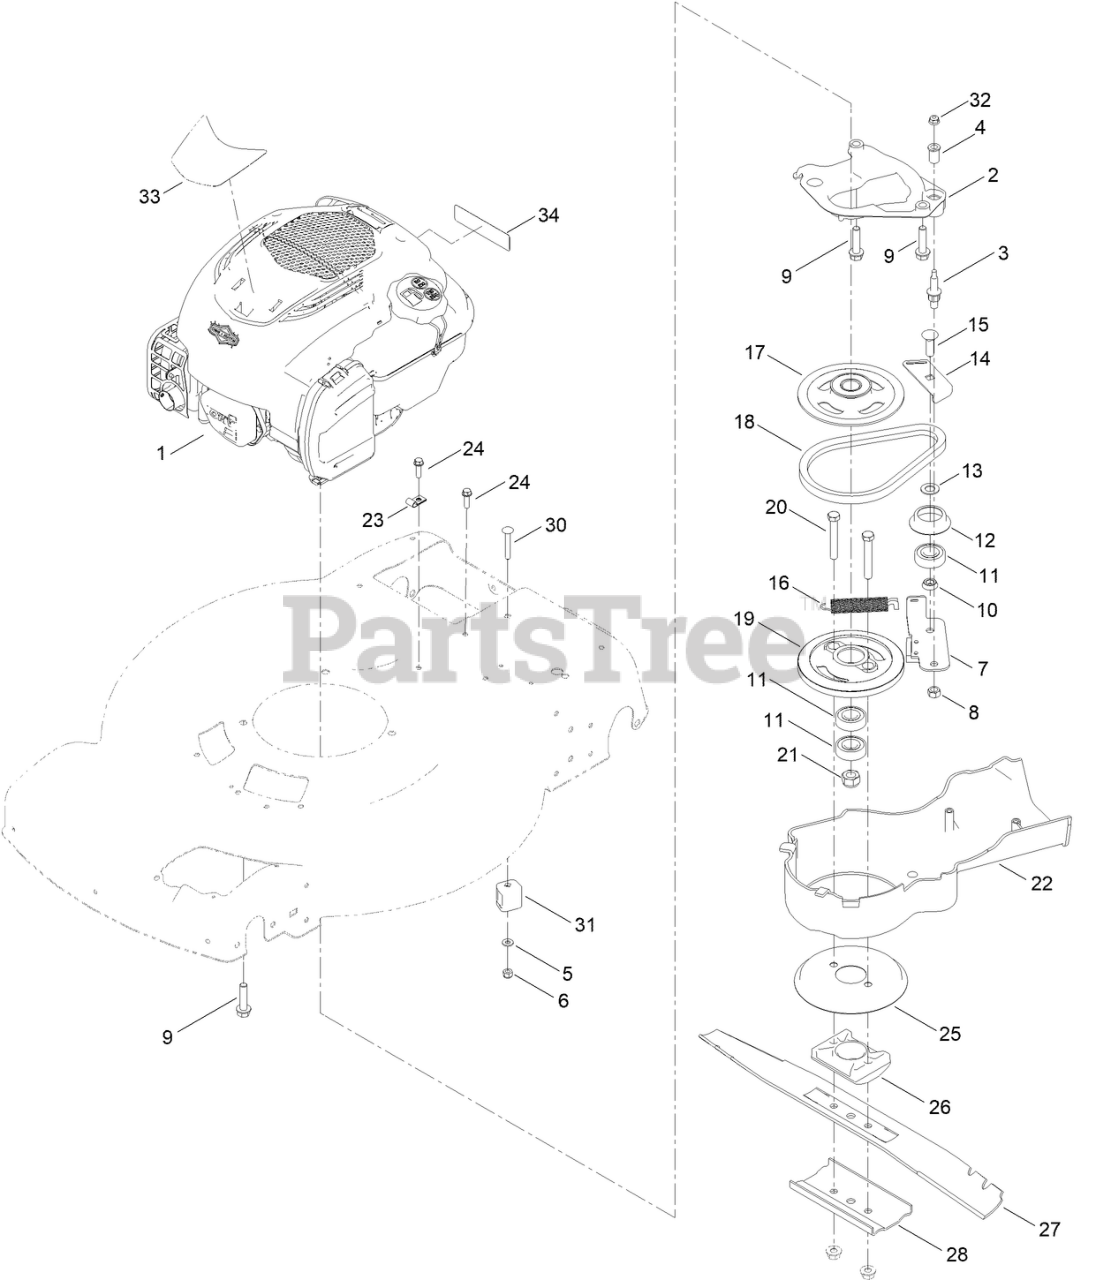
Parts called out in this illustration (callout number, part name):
1	ENGINE-BRIGGS 725 EXI BBC SS
2	PLATE-ANCHOR
3	BOLT-SHOULDER
4	BUSHING
5	WASHER-FLAT
6	NUT-HEX
7	PLATE-BRAKE
8	LOCKNUT
9	SCREW-HWH
10	SPACER-BEARING
11	BEARING-BALL
12	RETAINER-BELT
13	SPACER
14	PLATE-GUIDE
15	SCREW-CARR
16	SPRING-TENSION, BRAKE
17	PULLEY
18	BELT
20	SCREW-HH
21	NUT-HEX
23	CLIP-CLOSED, INSULATED
24	SCREW-PLASTITE, HWH
26	SUPPORT-BLADE
27	BLADE-22 INCH
28	SUPPORT-BLADE
30	BOLT-CARR
31	ANCHOR-CABLE
32	NUT-FLANGE, NI
33	DECAL- BRIGGS, 725 EXI SS
34	DECAL-ARRESTOR, SPARK
